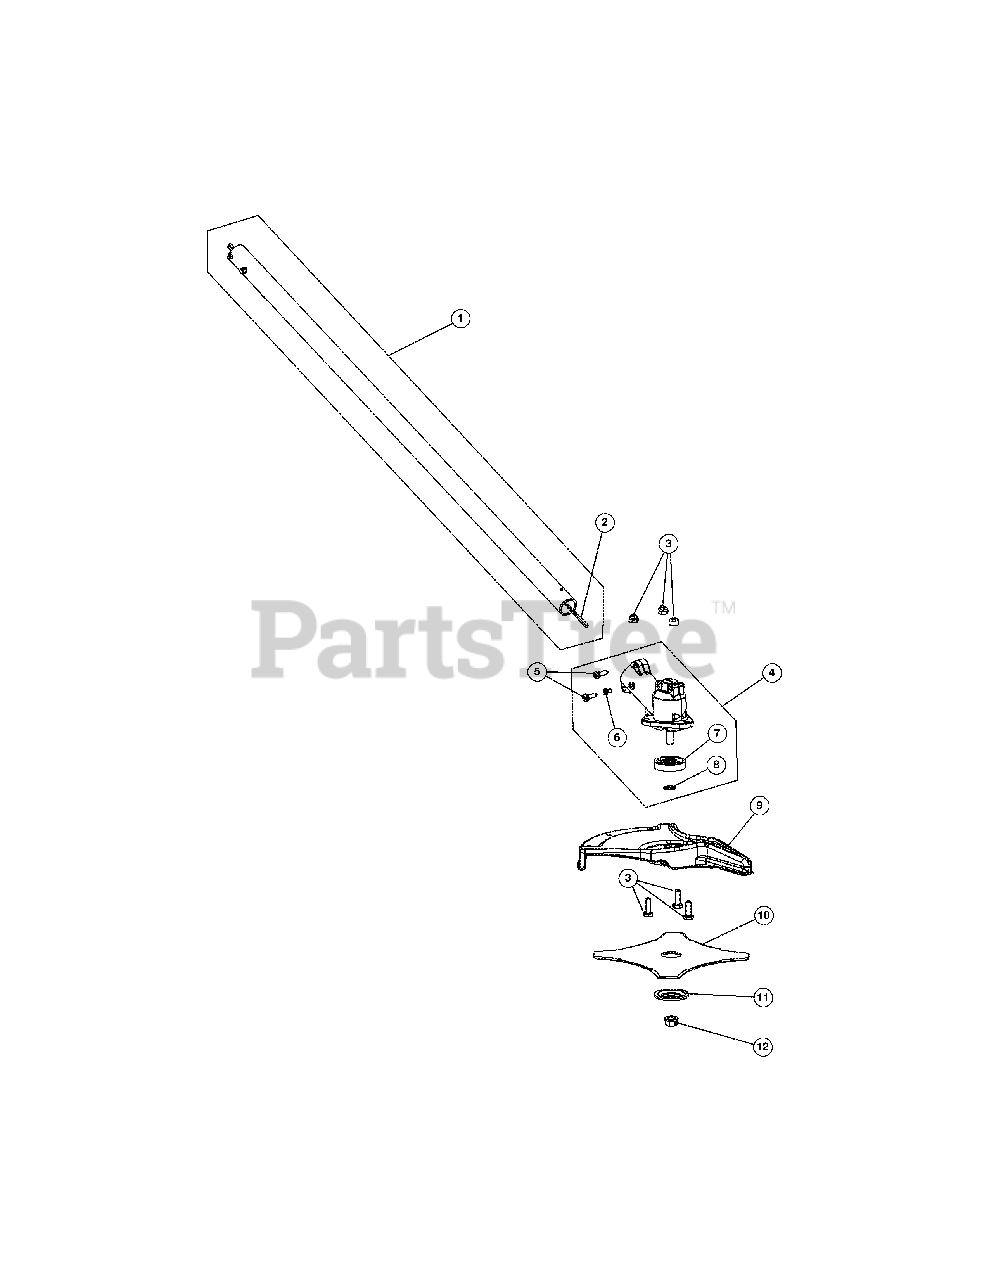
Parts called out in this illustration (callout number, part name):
1	Lower Drive Shaft Housing Assembly (Incl. Ref No. 2)
2	Lower Flexible Drive Shaft
3	Shield Mount Screw Assembly
4	2-Piece Gear Box Assembly (Incl. Ref No. 5-8)
5	Gear Box Mounting Hardware
6	Anti-Rotation Screw
7	Blade Driver
8	Palnut
9	Blade Shield/Shield Mount
10	4-Tooth Blade
11	Retaining Washer
